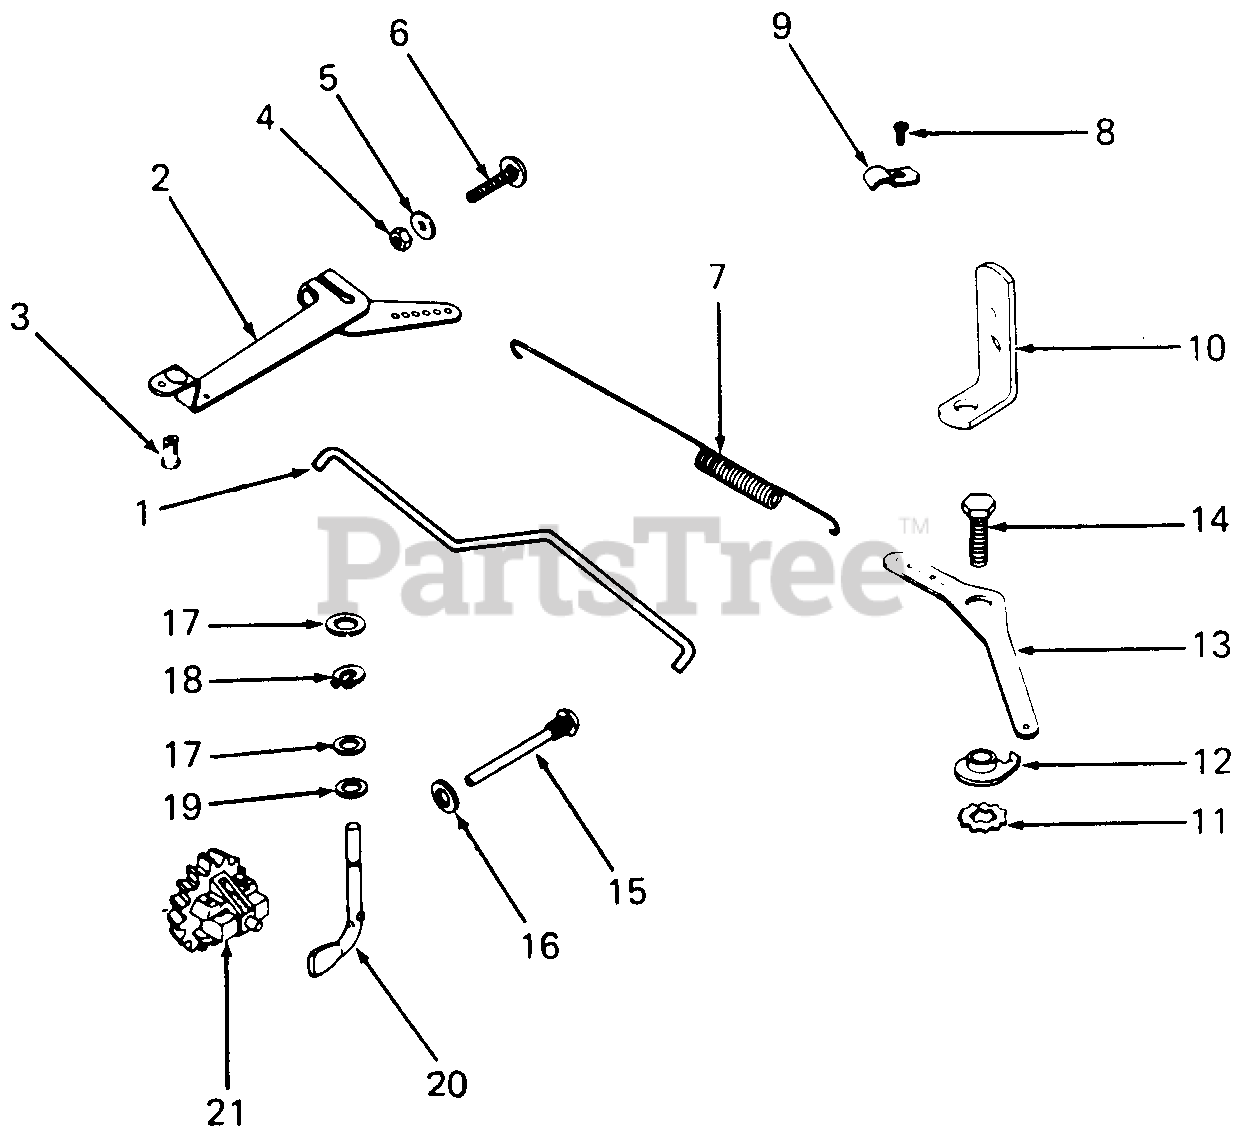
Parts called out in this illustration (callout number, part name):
1	Linkage, Governor
2	Arm, Governor
3	Bushing, Linkage Retaining
4	Nut, Hex, 1/4-20
5	Washer, Plain, 1/4
6	Screw, RH Sq Neck, 1/4-20 X 1.0 Lg
7	Spring, Governor
8	Screw, Hex Cap, #10-24 X 7/16 Lg
9	Clamp, Cable
10	Bracket, Throttle Cable
11	Washer, Lock
12	Stop, Governor
13	Lever, Speed Control
14	Screw, Hex Cap, 1/4-20 X .62 Lg
15	Pin, Governor Stop
16	Washer, Plain, 1/4
17	Washer, Plain, 1/4
18	Retainer, Governor
19	Washer, Plain, 1/4
20	Shaft, Governor Stop
21	Kit, Governor Gear
